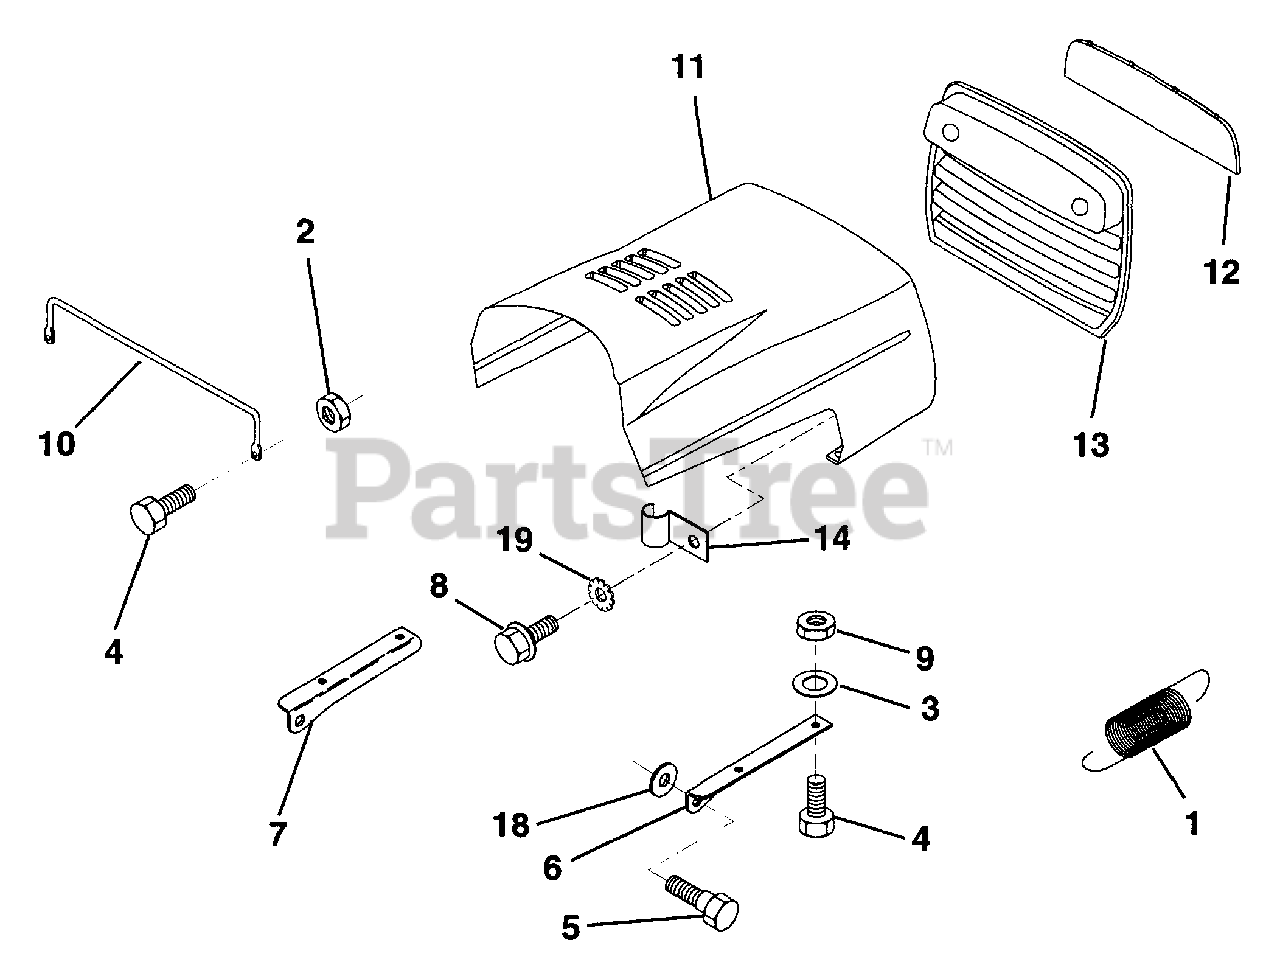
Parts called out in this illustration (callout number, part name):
1	Spring, Ext
2	Nut, Keps
3	Washer 9/32 x 7/8 x 16 Ga
4	Bolt, Fin Hex 1/4-20 x .75
5	Bolt, Shoulder 5/16-18
6	Bracket Hood RH
7	Bracket Hood LH
8	Screw, Sltd Hex Hd w/PI Washer
9	Nut, Lock w/Insert 1/4-20
10	Brace, Hood
11	Hood
12	Lens, Headlight Bar
14	Clip, Line Fuel
18	Washer 11/32 x 11/16 x 16 Ga
19	Washer Lock 1/4 Ext/Int Tooth
